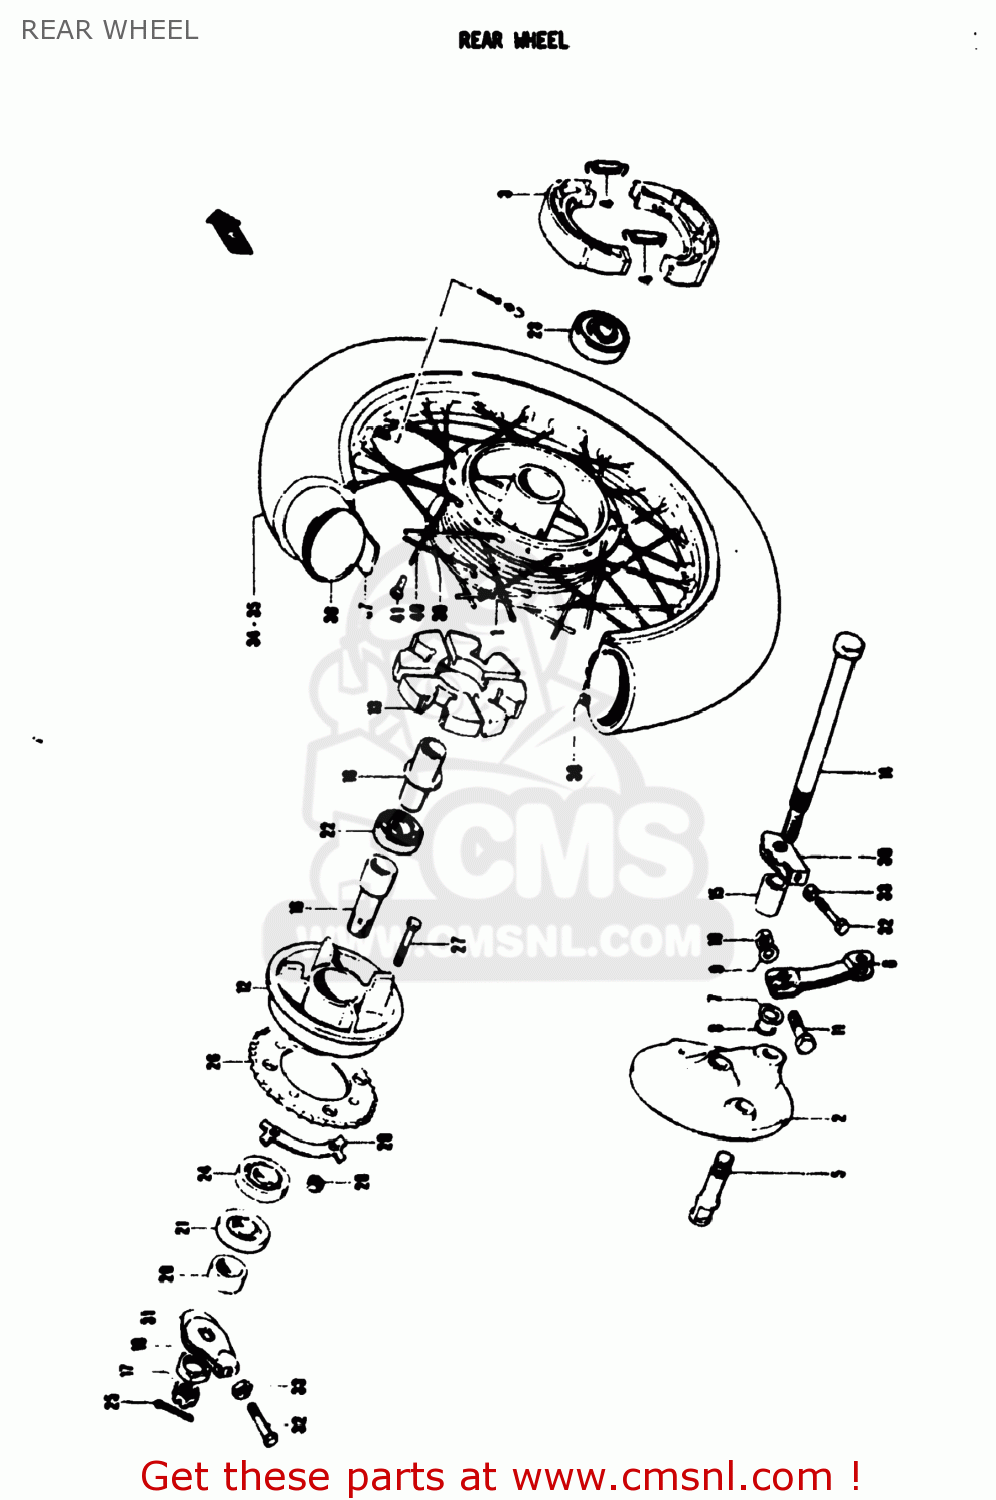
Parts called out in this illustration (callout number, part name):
1	HUB,REAR WHEEL
2	PANEL,REAR HUB
3	SHOE,BRAKE
4	SPRING(L:34)
5	CAM,FRONT BRAKE
6	LEVER,REAR BRAKE CAM
7	WASHER(12.5X20X1)
8	O RING(D:2.5,ID:11.4)
9	WASHER
10	NUT
11	BOLT
12	DRUM,REAR SPROCKET MOUNT
13	CUSHION,REAR DRUM
14	AXLE,REAR
15	SPACER(12.2X22X30.5)
16	SHAFT,RR SPROCKET DRUM
17	NUT
18	SPACER,REAR HUB BEARING
19	NUT
20	SPACER(17X25X10.5)
21	SEAL OIL(25X40X6)
22	BEARING, LH
23	BEARING, RH
24	BEARING
25	COTTER PIN
26	SPROCKET,REAR
27	BOLT(8X33.5)
28	NUT
29	WASHER
30	ADJUSTER,CHAIN
31	ADJUSTER,CHAIN
32	BOLT(6X38)
33	NUT
34	TIRE
35	TIRE,FRONT
36	TUBE ASSY,WHEEL INNER
37	PROTECTOR,WHEEL,INNER
38	SPOKE SET,REAR
39	SPOKE SET,REAR WHEEL
40	SPOKE SET,REAR WHEEL
41	NIPPLE,SPOKE
